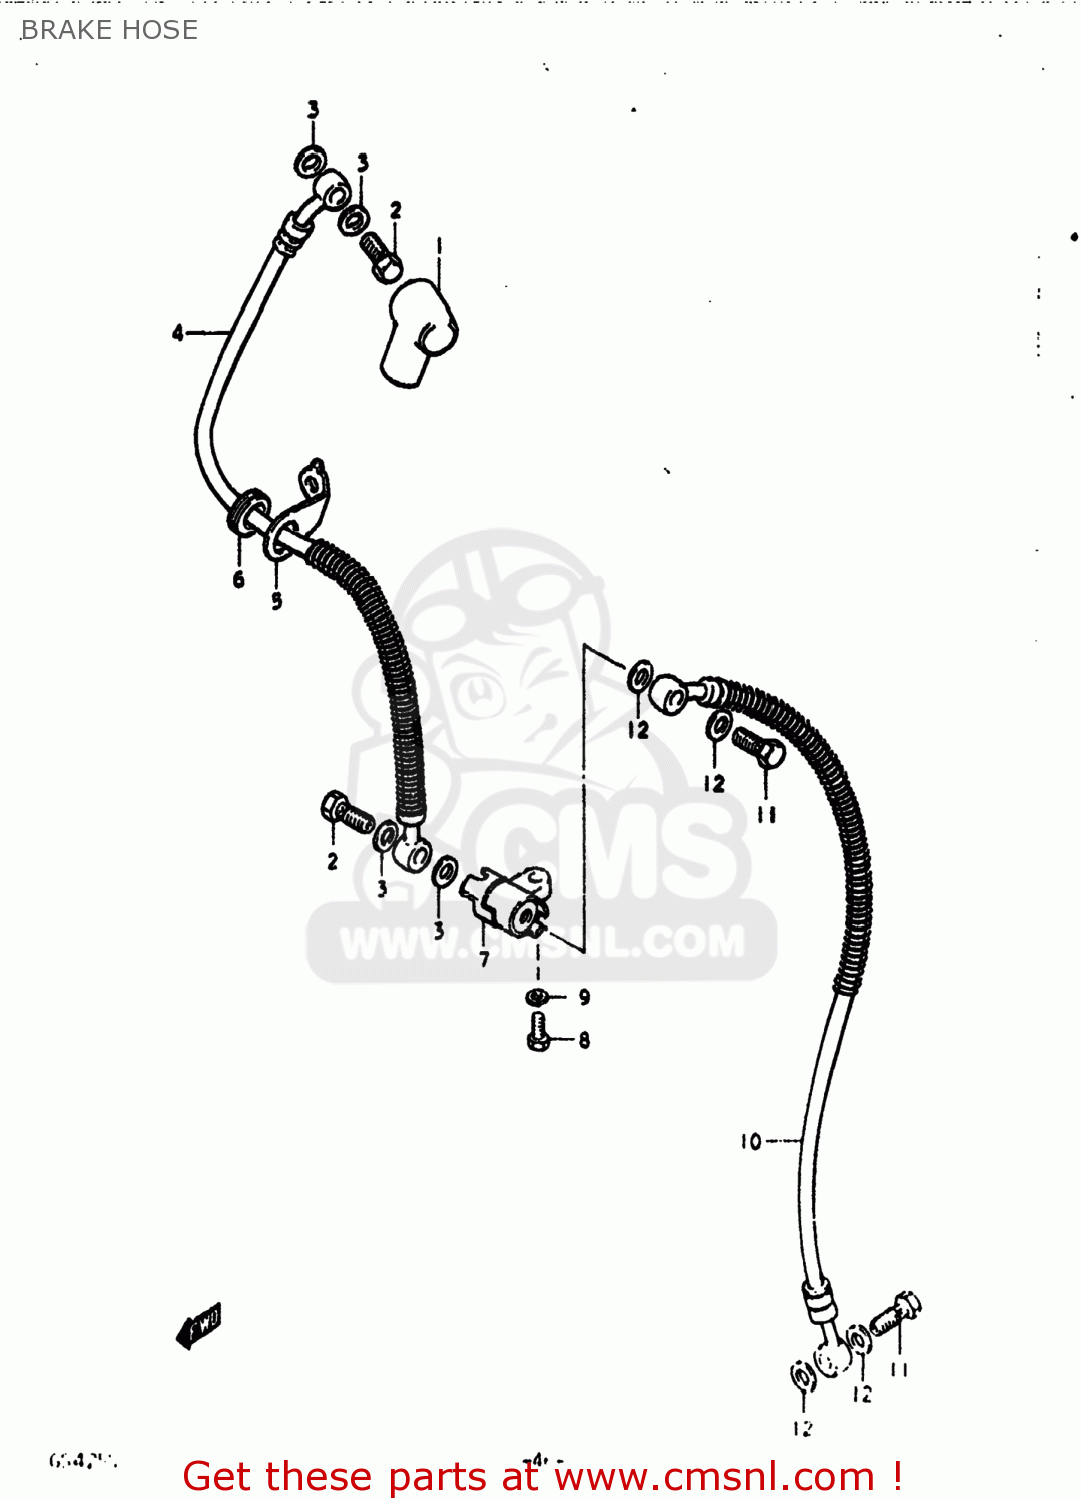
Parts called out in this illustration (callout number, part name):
1	BOOT,MASTER CYLINDER
2	BOLT UNION
3	WASHER
4	HOSE,FRONT BRAKE
5	GUIDE,BRAKE HOSE
6	GROMMET
7	JOINT,BRAKE HOSE
8	BOLT
9	LOCK WASHER
10	HOSE,FRONT BRAKE
11	BOLT UNION
12	WASHER
